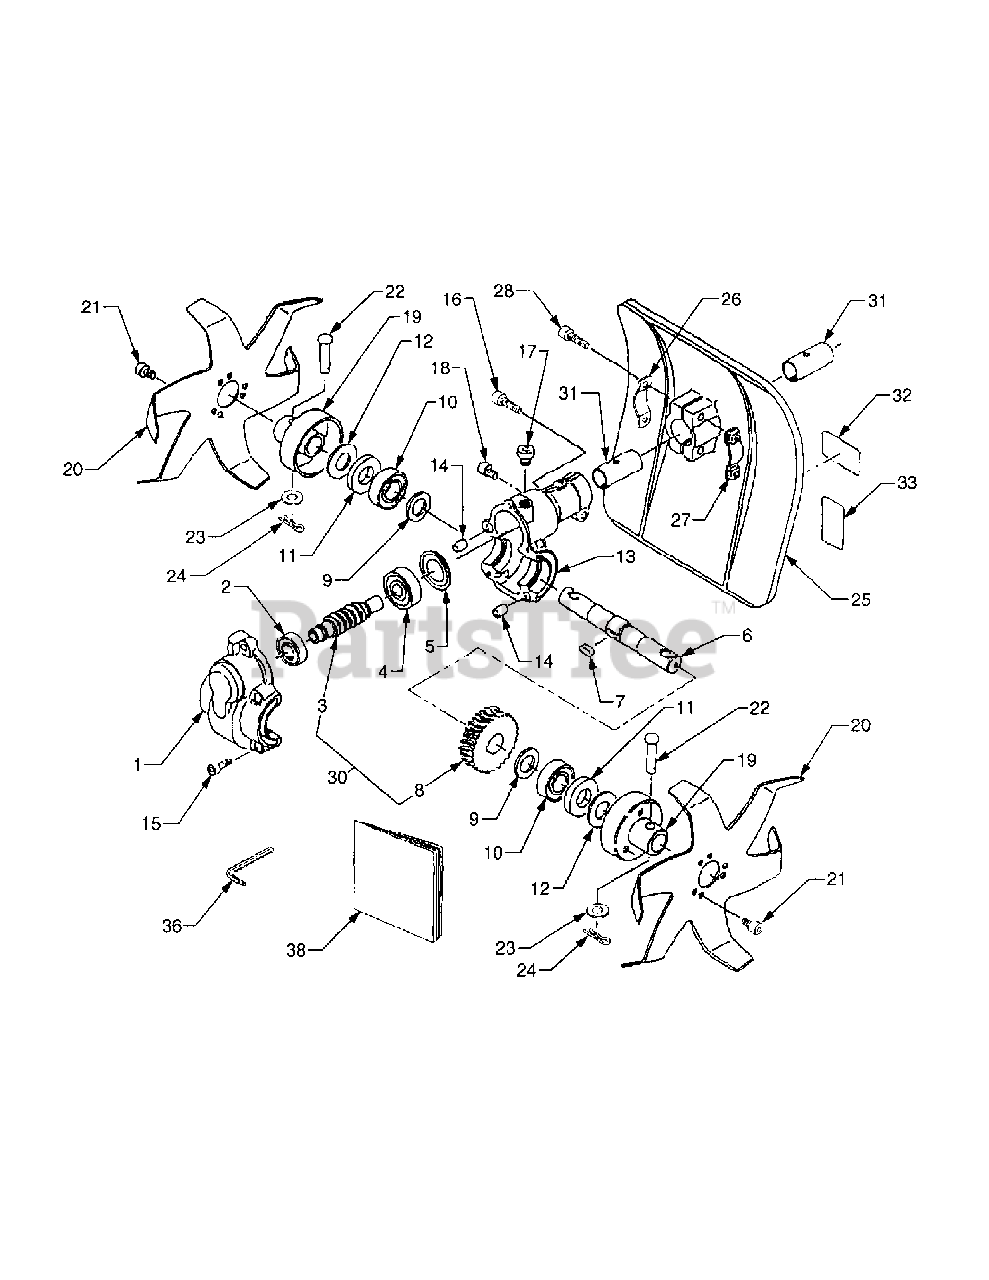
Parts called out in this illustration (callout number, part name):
1	Case, Gear
2	Bearing, Ball
3	Gear, Worm
4	Bearing, Ball
8	Gear, Wheel
10	Bearing, Ball
11	Seal, Oil
13	Case, Gear
14	Pin, Dowel
15	Bolt, M5 x 25
16	Bolt, M6 x 18
18	Bolt, M5 x 10
19	Holder, Rotor
21	Bolt, M6 x 12
24	Snap Pin
25	Deflector
28	Bolt, M6 x 30
30	Gear Assembly
32	Caution Plate
33	Caution Plate
36	Wrench, Torx
38	Instruction Book
